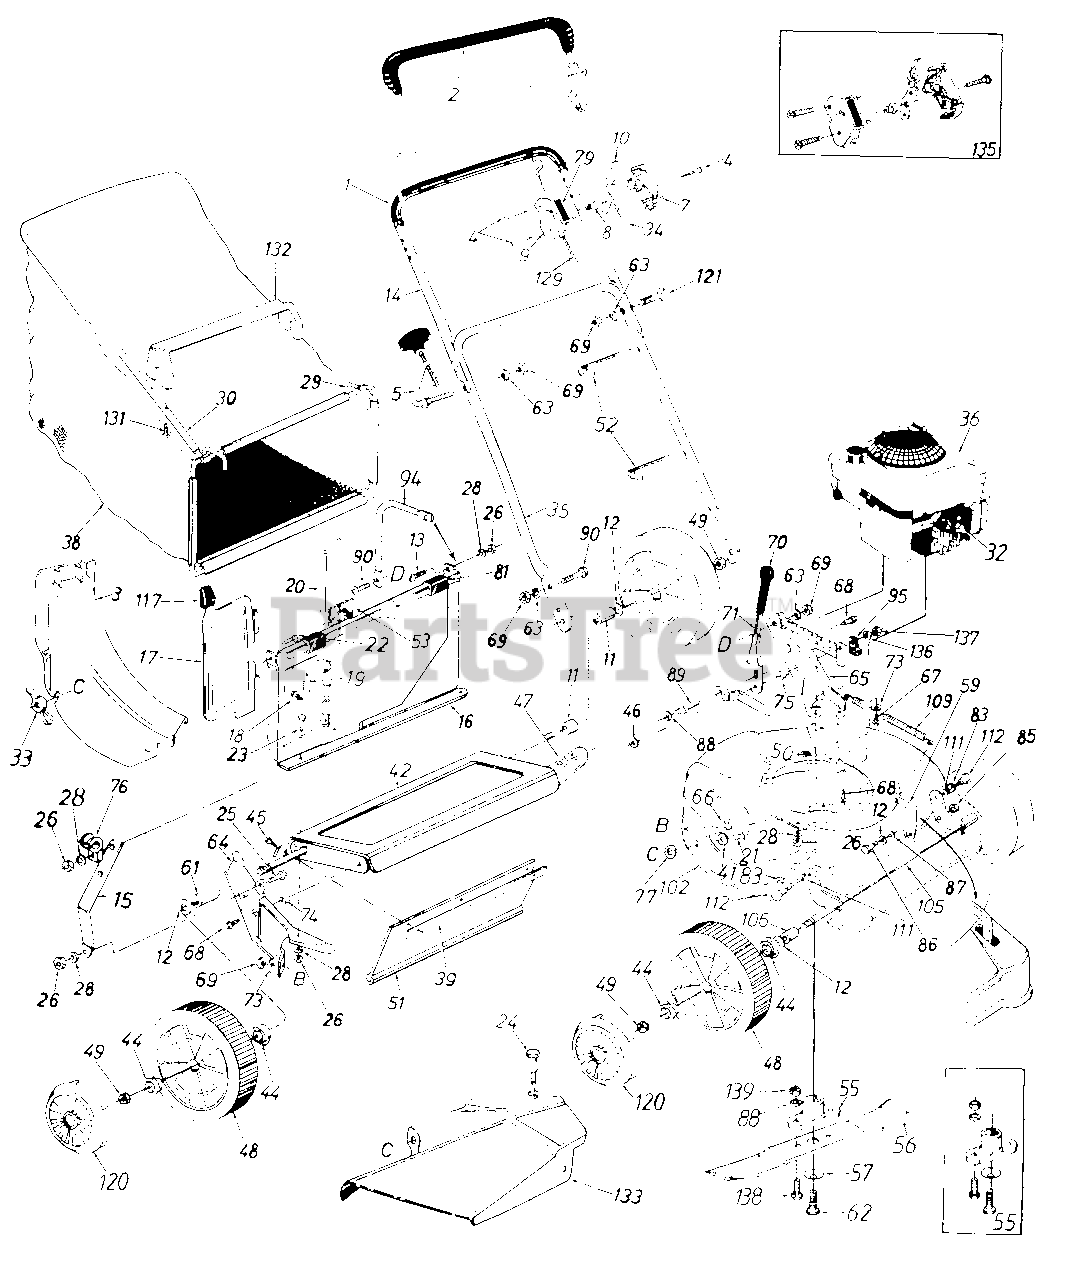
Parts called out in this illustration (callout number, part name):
1	Grip
2	Control Handle Ass'y.-L.H.
3	Top Discharge Chute Ass'y.
4	Truss Mach. Scr. #12 x 1.50" Lg.
5	Rope Guide Bolt
7	Control Panel Half
8	Control Disc Pin
9	Clutch Panel Half
10	Throttle Control Lever
11	Spacer .526" I.D. x .690" O.D. x .640" Lg.
12	Fl-Wash. .510" I.D. x .75"
13	Truss Mach. Scr. 1/4-20 x .62"
14	Upper Handle
18	Hex B-Tap Scr. #10 x .38"
19	Torsion Spring
20	Pivot Pin
21	Carriage Bolt 1/4-20 x .62"*
22	Truss Mach. Scr. 1/4-20 x .75" Lg.
23	Hex Bolt 1/4-20 x .50" Lg.
24	Shoulder Bolt .312 Dia. x .18 Lg. Special
25	Hex Bolt 1/4-20 x .62" Lg.
26	Hex Nut 1/4-20 Thd.
28	L-Wash. 1/4" I.D.*
32	Spark Plug Insulator
33	Wing Nut w/Washer
34	Throttle Control Wire 61"
35	Lower Handle
36	Engine
38	21" Top Discharge Grass Bag (Grey)
39	Retaining Strip
41	Fl-Wash. .344" I.D. x .62"
45	Hex AB-Tap Scr. 1/4 x .62"
46	Fl-Wash. .38" I.D. x 1.0"
47	Hex Jam Nut 3/8-24 Thd.
48	Wheel Ass'y.-Comp. 8" x 2"
49	Hex L-Nut 1/2-20 Thd.
51	Rear Flap 3.75" x 17.30" Lg.
52	Cable Tie
53	Foam Strip 1" Lg.
55	Blade Adapter Kit
56	21" Blade
57	Bell-Wash. .46" I.D.
59	Height Adj. Connecting Arm
61	Sleeve .526" I.D. x .69"
62	Hex Bolt 7/16-20 x 1.5" Lg. (Grade 5)
63	L-Wash. 5/16" I.D.*
64	R.H. Handle Wheel Brkt. Ass'y.
65	L.H. Handle Wheel Brkt. Ass'y.
66	Carriage Bolt 5/16-18 x .62"*
67	Hex Wash. Hd. B-Tap Scr. 5/16-18
68	Hex Wash. Hd. TT-Tap Scr. 3/8-16
69	Hex Nut 5/16-18 Thd.*
71	Height Adj. Lever
73	Bell-Wash. 5/16" I.D.
74	Spacer .383" I.D. x .503" O.D.
75	Shld. Spacer. 500" Dia.
76	Rope Guide
77	Bolt Retainer 1/4 x .50" O.D.
79	Control Label
81	Panel Clip
83	Flanged Nyliner Brg.
85	Hex Jam Nut 3/8-16 Thd.
86	Shld. Bolt .50" Dia. x .295"
87	Bell-Wash. .515" I.D. x 1.0" O.D.
88	L-Wash. 3/8" I.D.*
89	Shld. Pin 3/8-24 x 1.43" Lg.
90	Truss Mach. Scr. 5/16-18 x .75"
94	Catcher Panel Support Arm
95	Clamp
106	Sleeve .526" I.D. x .690" O.D. x .880" Lg.
109	Extension Spring 8" Lg.
111	Intern. L-Wash. 3/8 I.D.*
112	Shld. Bolt .575" Dia. x .42"
117	Door Grip
120	Hub Cap
121	Curved Carr. Bolt 5/16-18 x 1.38" Lg.
129	Control Cable 46" Lg.
131	Hex AB-Tap Scr. #12 x 1.25"
132	Bag Handle
133	Side Chute Deflector Ass'y.
135	Kit-Control Housing Comp.
136	Fl-Wash. .385" I.D. x .87" O.D.
137	Hex Patch L-Nut 3/8-24 Thd.
138	Hex Bolt 3/8-24 x 1" Lg.
139	Hex Nut 3/8-24 Thd.
